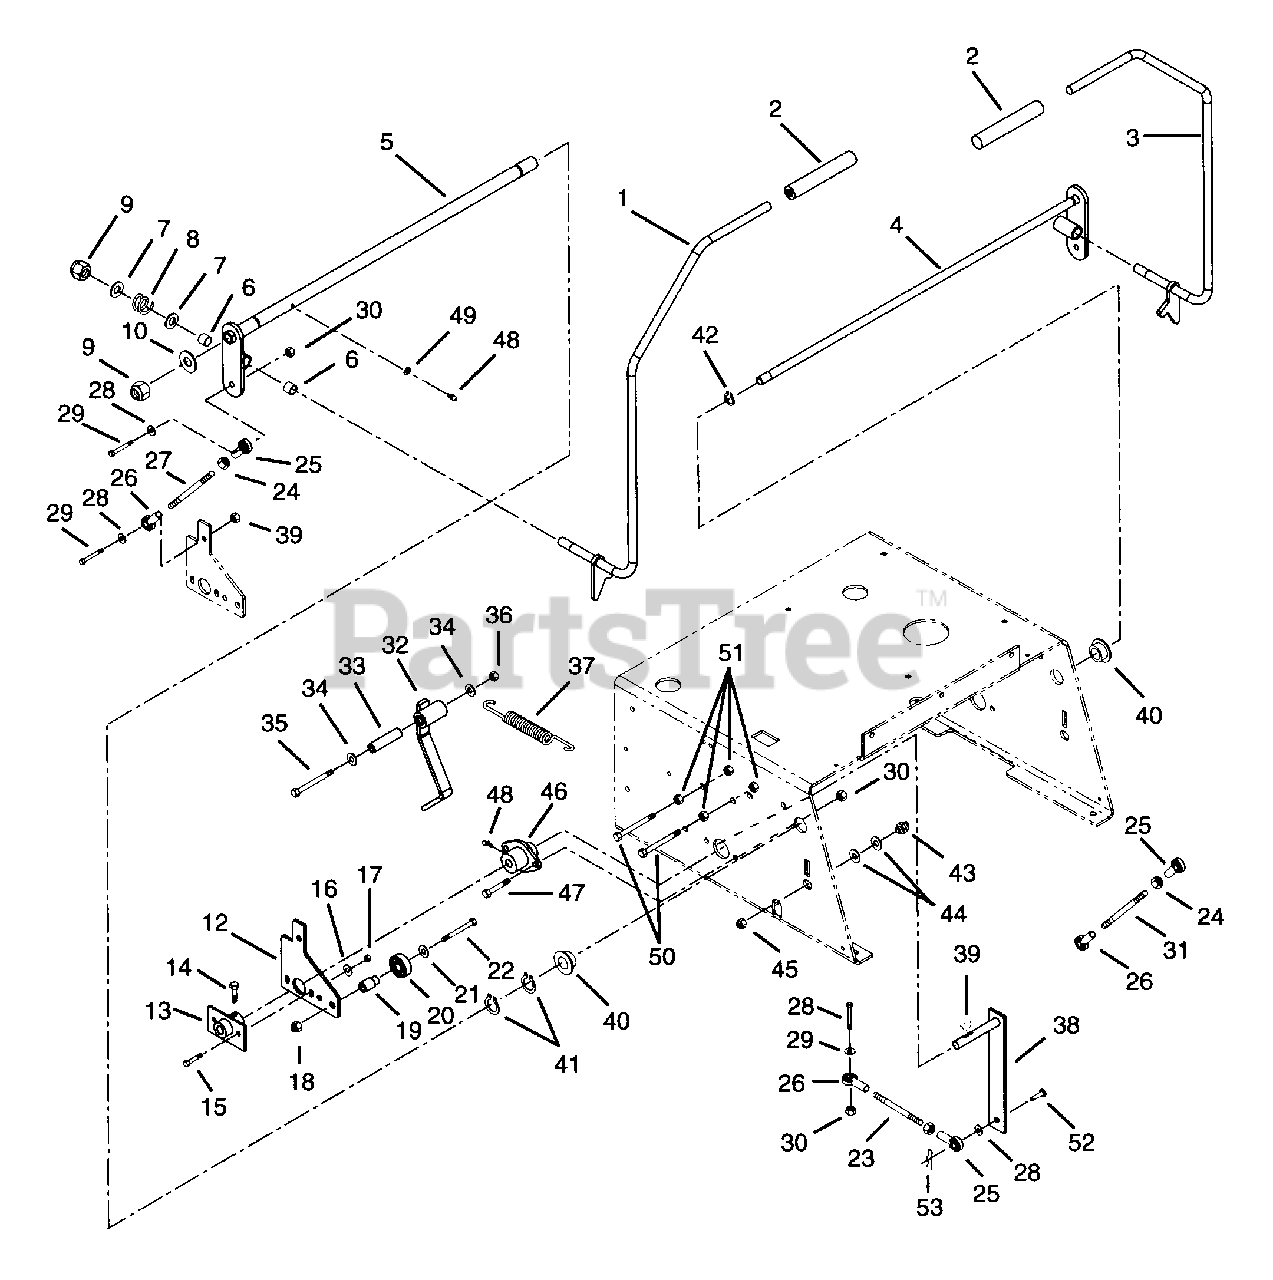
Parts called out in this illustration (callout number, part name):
1	RH STEER-CONTROL LEVER
3	LH STEER-CONTROL LEVER
4	WLDMNT, ROD LH
5	WLDMNT, TUBE RH
6	BUSHING, NYLON .5 X .62 X .5LG
7	WASHER, PLASTIC .12X.53.1.12
8	SPRING, COMPRESSION
9	NUT-LK-CTR-JAM .50-13 YWZC(ND)
10	WSHR-FL-STL .531X1.062X.095
11	PIN-HAIR INT .08X.18X1.18
12	ARM,SPEED CONTROL
13	ARM, SPEED CONTROL
14	BLT-HEX .25-20X.50 PL GR5
15	BLT-HEX .25-20X.75 PL GR5
16	WSHR-FL-STL.281X.62X.065 PL
17	NUT-LK-NYL .250-20 PL
18	NUT-LK-NYL .375-16 PL
19	HUB, BRG. MOUNT
20	BRG-BALL .500X1.375X.437
21	WSHR-FL-STL.406X.812X.065PL
22	BLT-HEX .38-16X2.00 PL GR5
23	ROD TRANS CONTROL RH
24	NUT-HEX .312-24 PL
25	ROD END, 5/16 RH - FEMALE
26	ROD END, 5\16 LH - FEMALE
27	ROD, CONTROL LEVER
28	WSHR-FL-STL.344X.688X.065PL
29	BLT-HEX .31-18X1.25 PL GR5
30	NUT-LK-NYL.312-18 PL
31	ROD, TRANS CONTROL LH
32	WLDM'T, NEUTRAL DETENT
33	BUSH.,S.385X.610X1.80 ST
34	WSHR-FL-STL.406X.812X.065PL
35	BLT-HEX .38-16X2.75 PL GR5
36	NUT-LK-NYL .375-16 PL
37	SG-TENS .085X.60X5.13 WLD8.3
38	WLDMNT, PUMP CONTROL
39	KEY-WDRF .125X.75
40	BSHG-FLG .762X1.0X.580X1.48 NY
41	RG-RTNG-EXT .689X.078
42	RG-RTNG-EXT .500X.460
43	SWITCH, NEUTRAL START N.O.
44	WSHR-FL-STL.563X1.37X.109PL
45	NUT-STAMPED .56-18
46	BUSHING, FLANGED
47	BLT-HEX .31-18X1.00 PL GR5
48	FTG-LUBE .25-28X.256 YWZC
49	WSHR-FL-STL .265X.500X.087 PL
50	BLT-HEX .38-16X3.00
51	NUT-HEX .375-16
52	PIN-CLEV .312X.822 HDND PL
